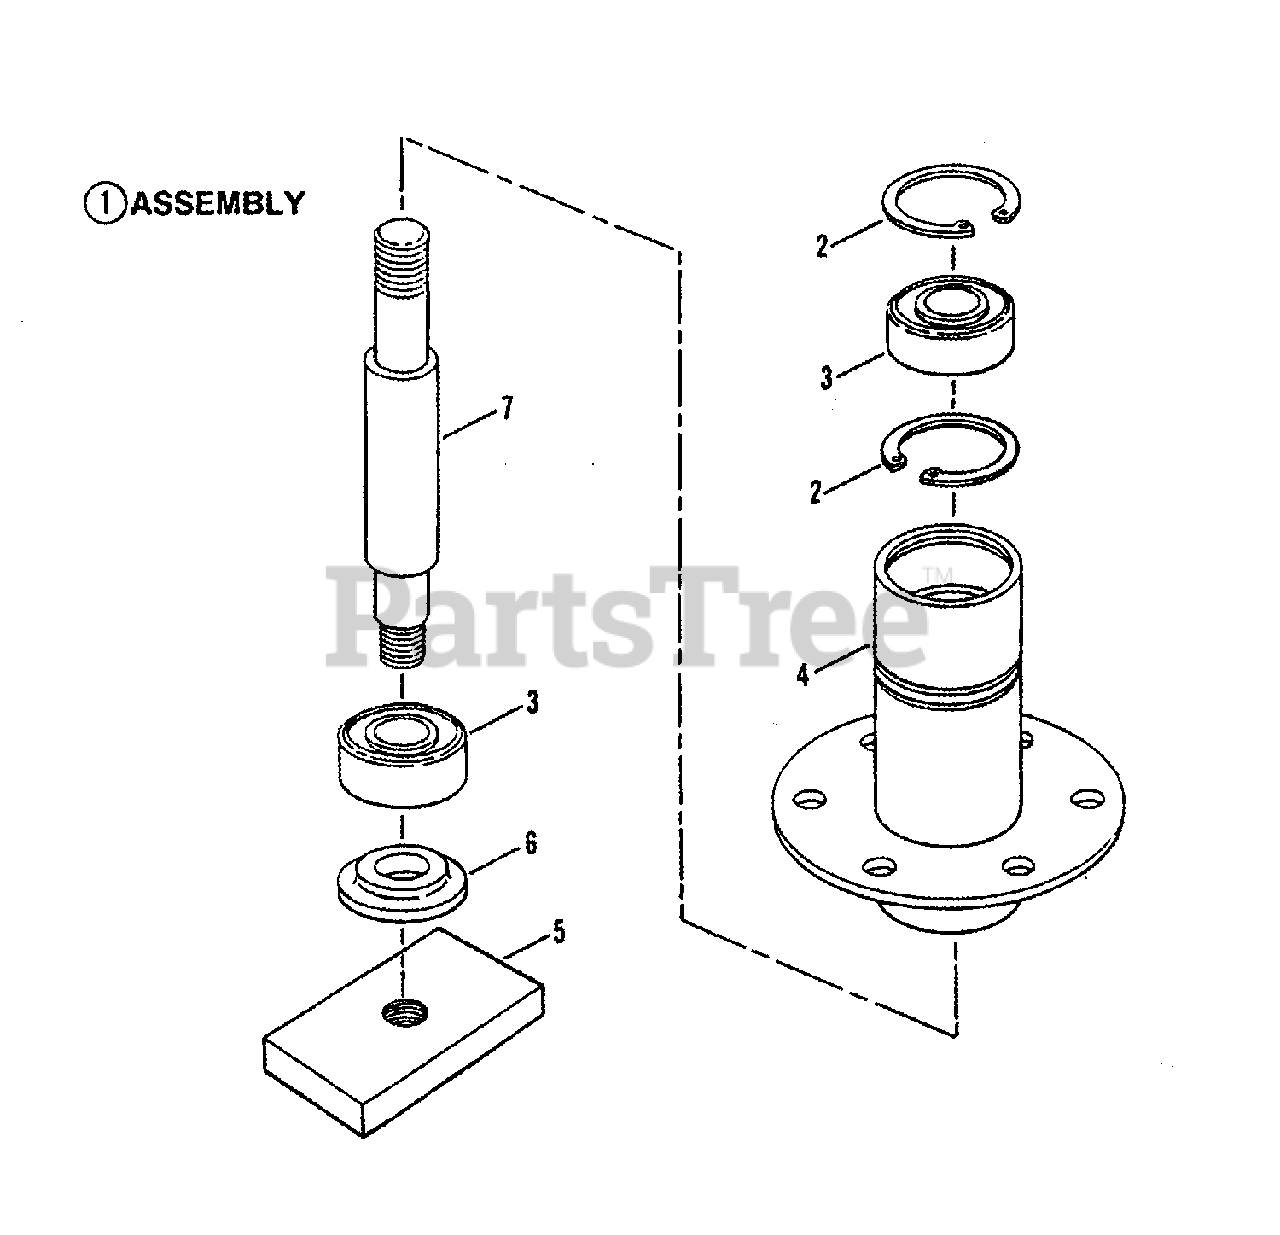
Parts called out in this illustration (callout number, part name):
1	ASSEMBLY, Spindle Housing, 42" Deck (Includes items 2 thru 7)
2	RING, 1-3/4" Retaining
3	BALL BEARING, 3/4" I.D.
4	WELDMENT, Spindle Housing
5	BLADE HOLDER
6	WASHER, Spindle
7	SHAFT, Spindle (6.5" long)
